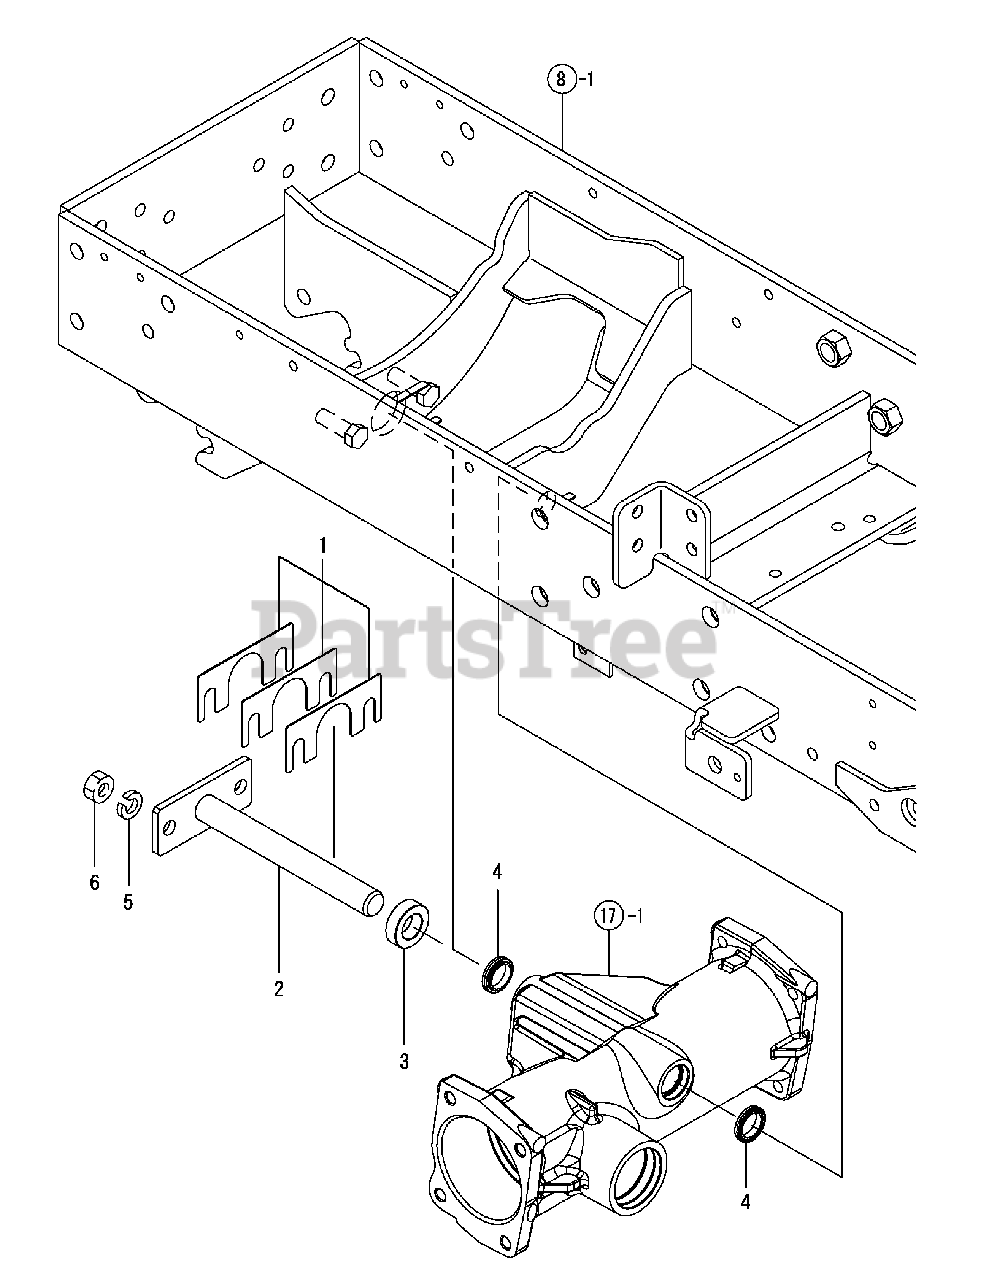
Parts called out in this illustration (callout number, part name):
1	SHIM SET, CENTER PIN
2	PIN ASSY, CENTER
3	COLLAR, 22X38X11.5
4	DUST SEAL 22X30X6
5	SPRING WASHER 12
